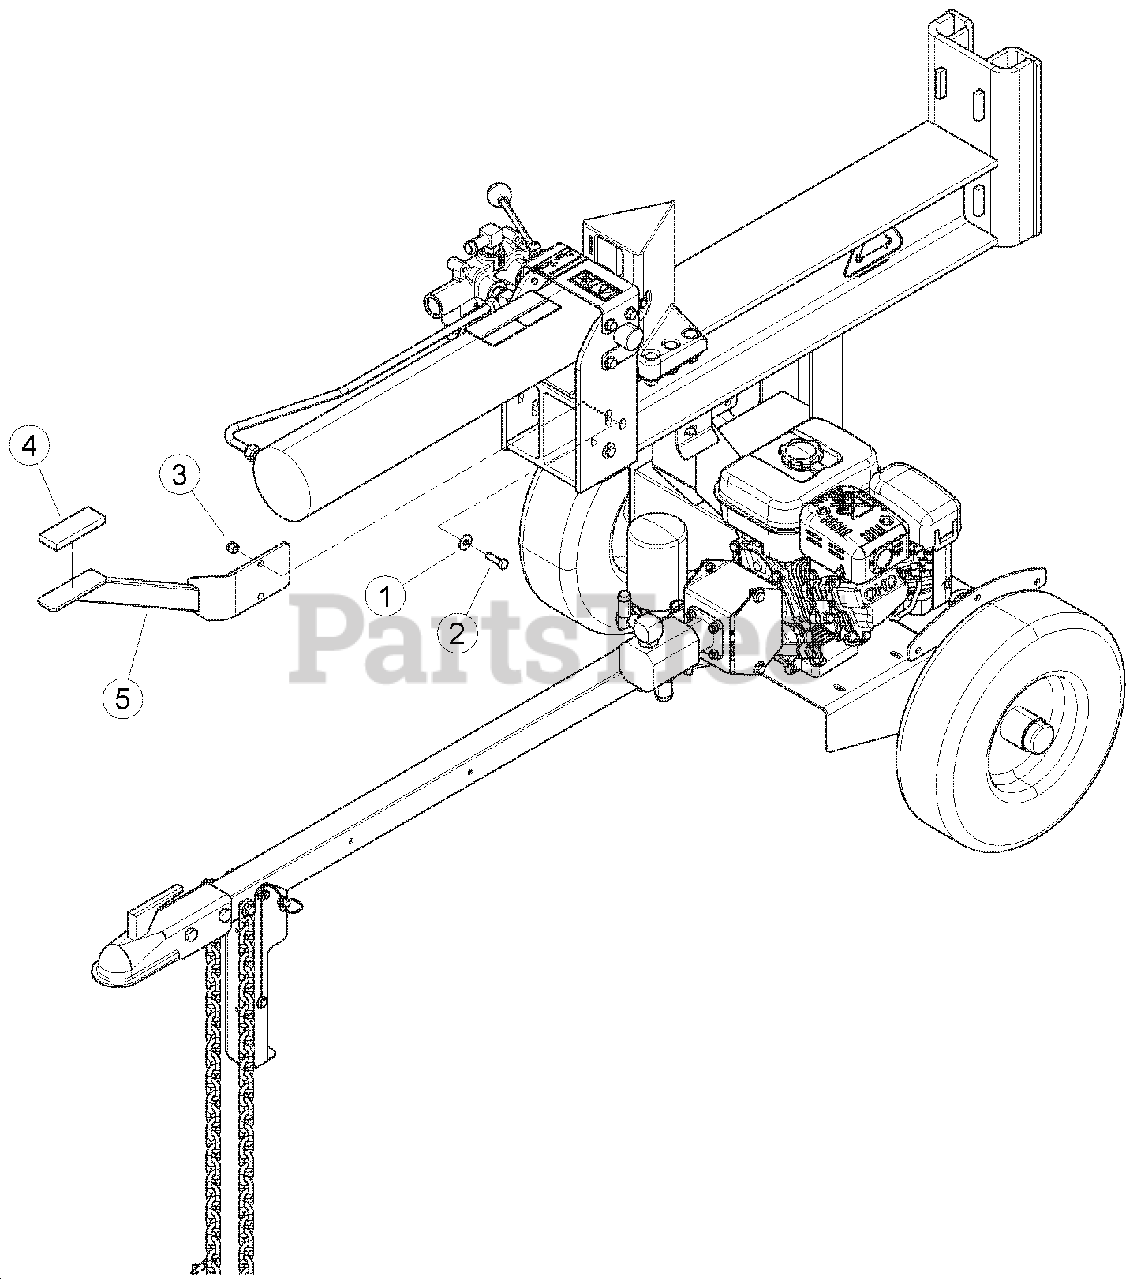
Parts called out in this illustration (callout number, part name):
1	WASHER, 3/8 FLAT ZP
2	BOLT, 3/8 X 1-1/4 HEX HD GR5 ZP
3	NUT, 3/8 NE NYLOCK ZP
4	PAD, FOAM LS CYLINDER BRACE
5	WELDMENT, LS CYLINDER BRACE
